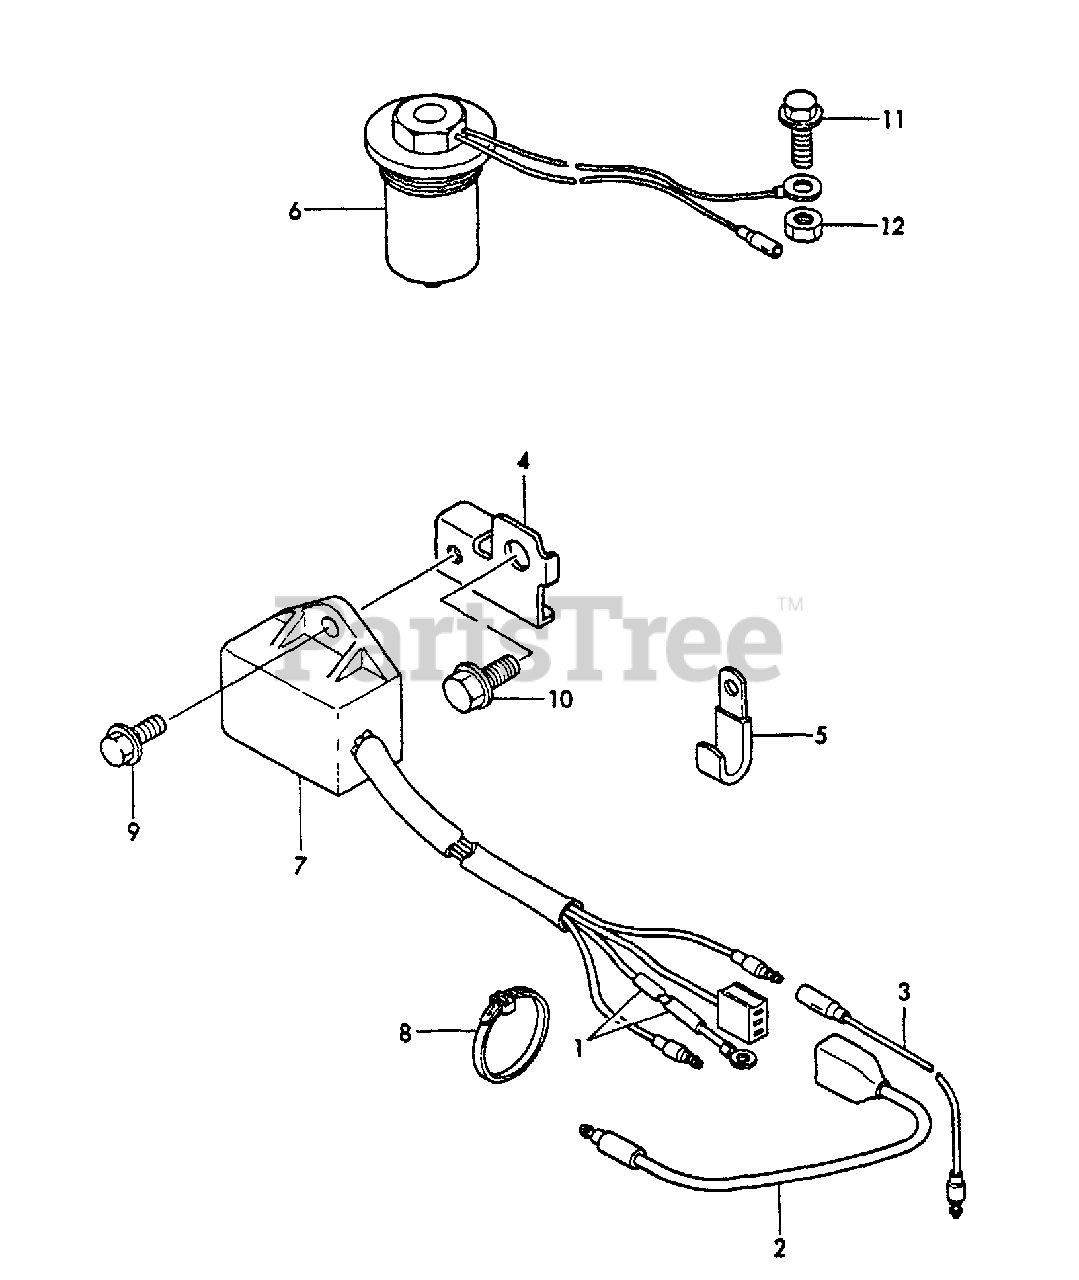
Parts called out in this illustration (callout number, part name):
1	TUBE, INSULATOR
2	WIRE
3	WIRE, SENSOR UNIT
4	STAY, SENSOR UNIT
5	CLAMP
6	SENSOR, OIL LEVEL
7	SENSOR UNIT, OIL
8	CLAMP
9	BOLT - 6×12 -- PLATED
10	BOLT - 8×14 -- PLATED
11	BOLT - 6×16 -- PLATED
12	LOCKNUT - 6 -- PLATED
